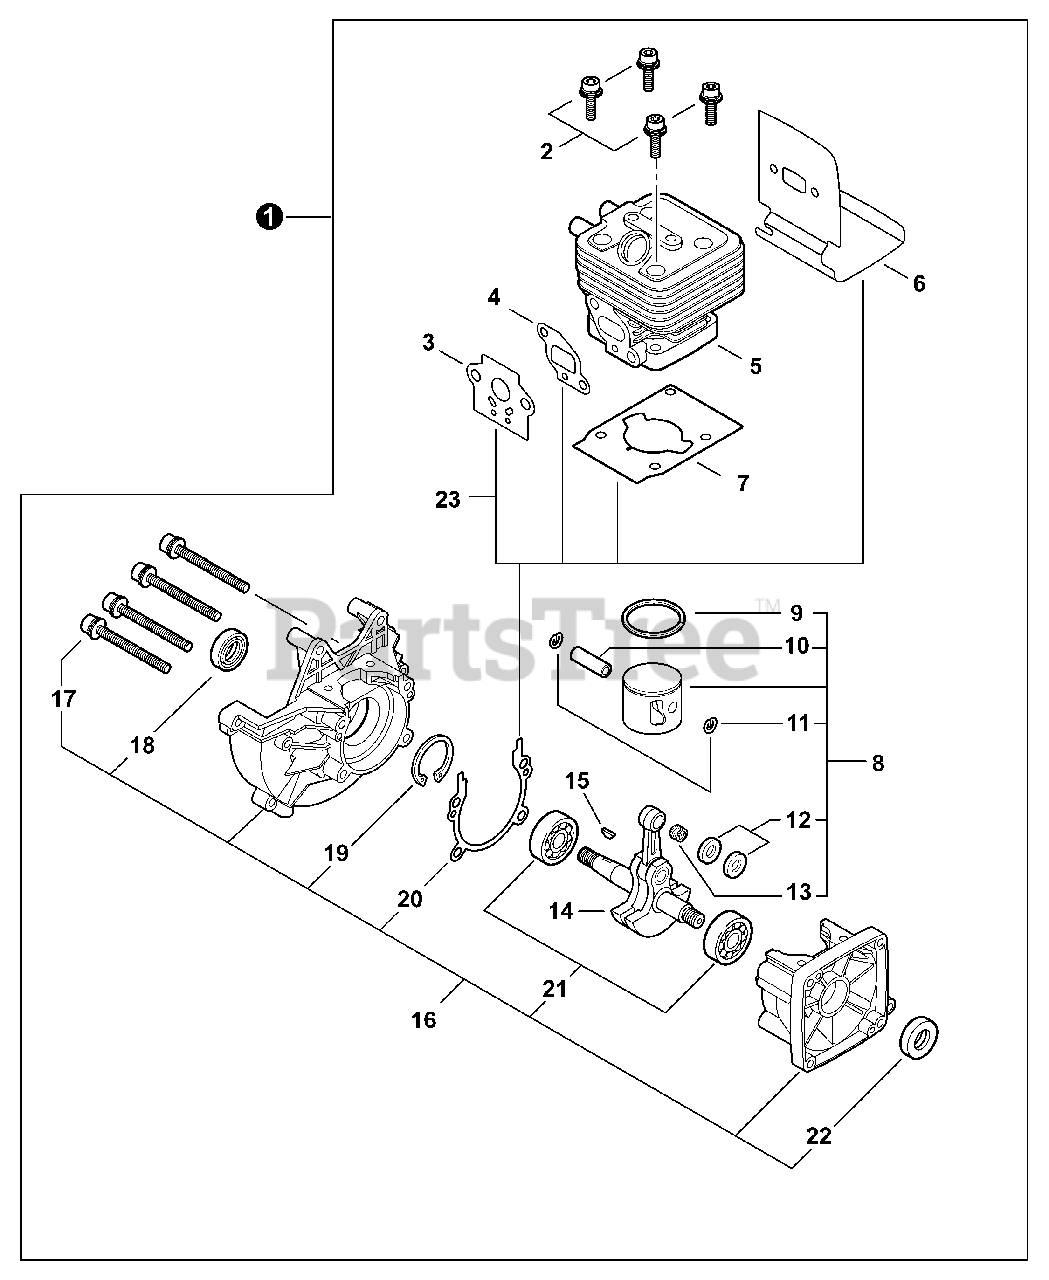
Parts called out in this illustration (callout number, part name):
1	SHORT BLOCK
2	SCREW 5×25
3	GASKET, INTAKE
4	GASKET, INTAKE
5	CYLINDER
6	HEAT SHIELD, EXHAUST
7	GASKET, CYLINDER
8	PISTON KIT
9	RING, PISTON
10	PIN, PISTON
11	RING, SNAP
12	WASHER, THRUST
13	BEARING, NEEDLE 9
14	CRANKSHAFT ASSY
15	KEY, WOODRUFF
16	CRANKCASE KIT
17	BOLT 5×28
18	SEAL, OIL 12
19	RING, SNAP Ø32
20	GASKET, CRANKCASE
21	BEARING, BALL - 6201 C3
22	SEAL, OIL 12
23	GASKET KIT
